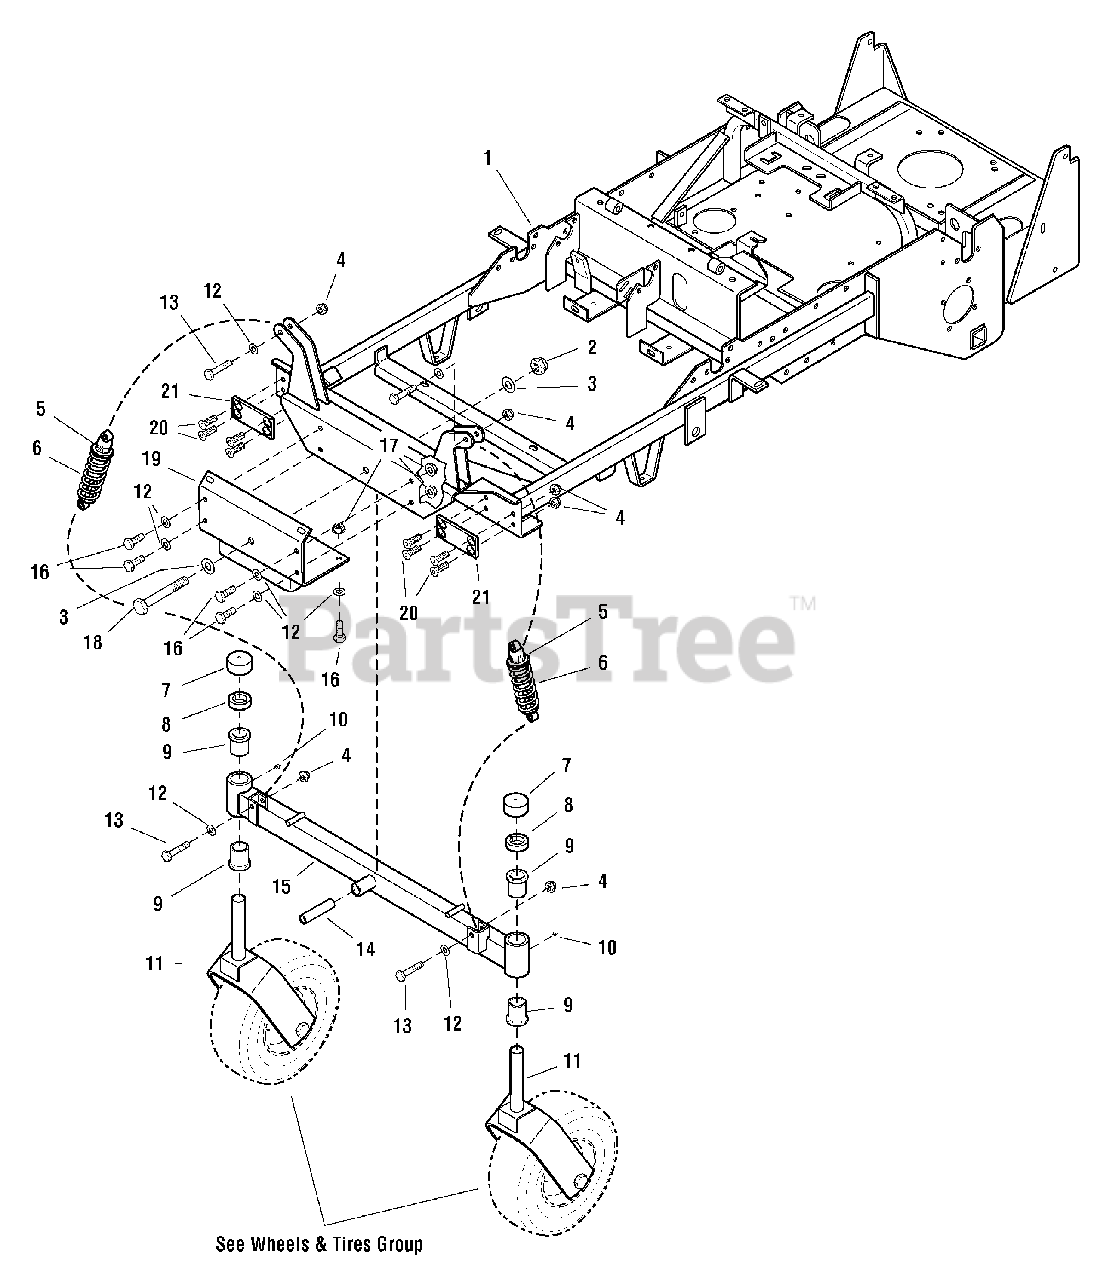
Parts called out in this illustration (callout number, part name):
1	FRAME ASSEMBLY, Main, Orange
1	FRAME ASSEMBLY, Main, Red
2	NUT, Hex Nylon Lock, 1/2-13
3	WASHER, SAE, 1/2
4	NUT, Hex Nylon Lock, 5/16-18
5	O-RING
6	SHOCK ABSORBER
8	COLLAR, Split, 1"
9	BUSHING, Flange
10	FITTING, Grease
11	YOKE, Caster
12	WASHER, SAE, 5/16
13	CAPSCREW, Hex Head, 5/16-18 X 1-3/4
14	SPACER, .51 X .75 X 3.375
15	FRAME ASSEMBLY, Pivot
16	CAPSCREW, Hex Head, 5/16-18 X 3/4
17	NUT, Hex Serrated Flange, 5/16-18
18	CAPSCREW, Hex Head, 1/2-13 X 5
19	HANGER ASSEMBLY, Deck, Orange
19	HANGER ASSEMBLY, Deck, Red
20	SCREW, 5/16-18 X 1, PHILLIPS HD, BZ
21	FRICTION PLATE
